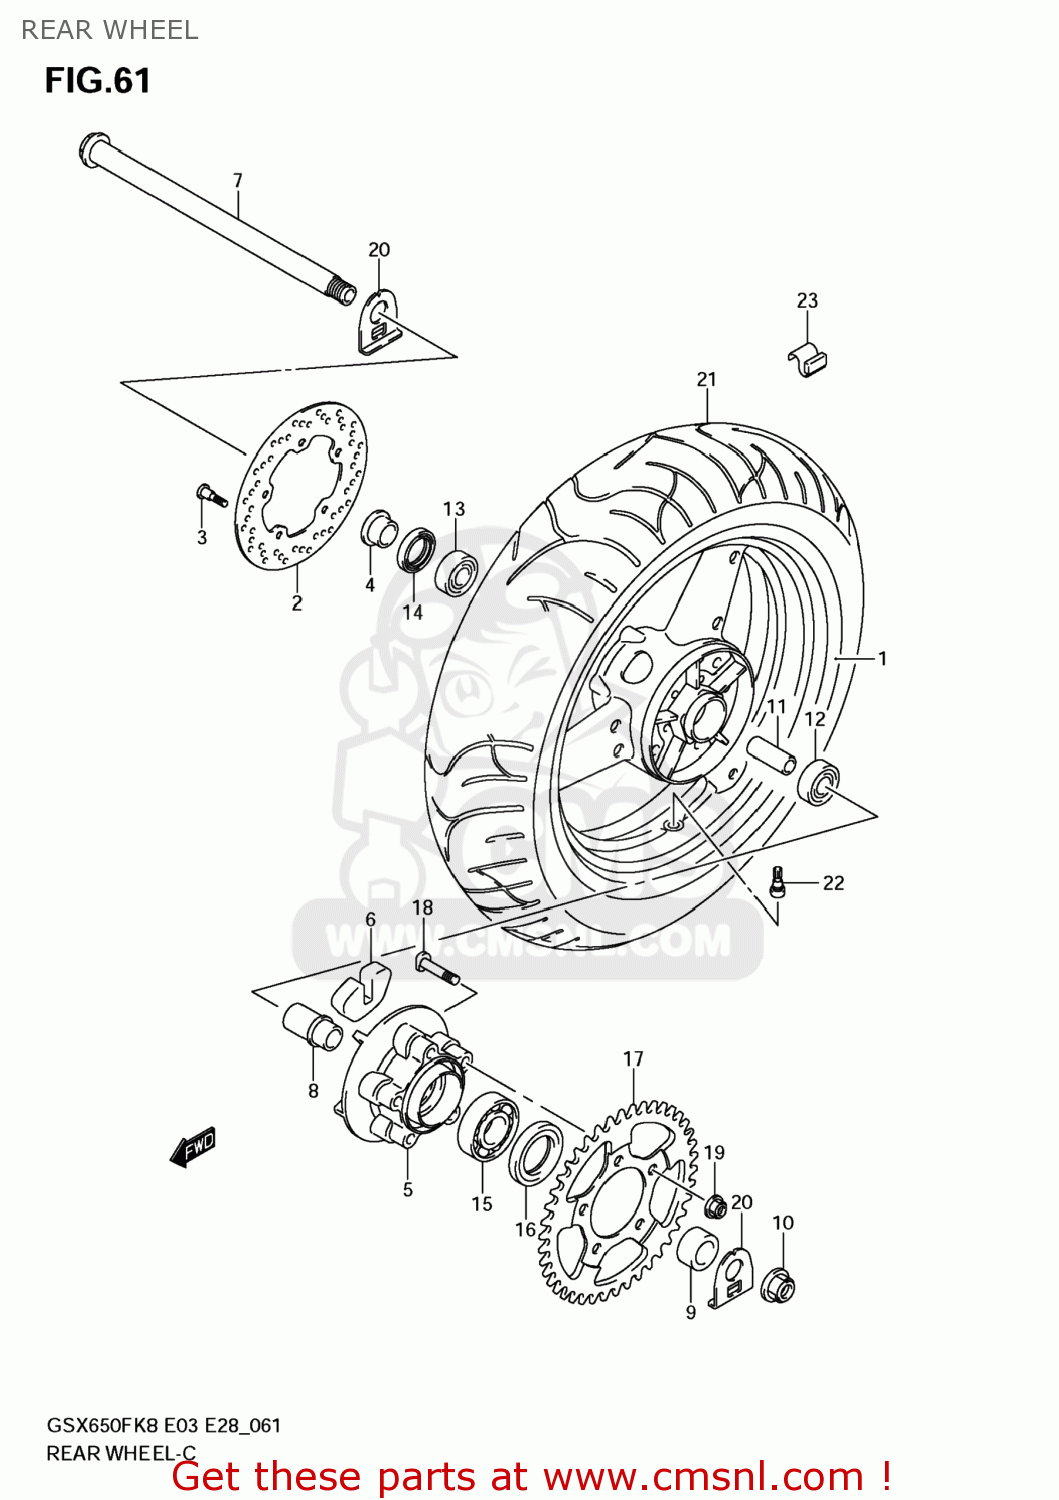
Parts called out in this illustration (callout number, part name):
1	WHEEL,RR(17M/CXMT5.00)
2	DISC,RR BRAKE
3	BOLT(8X33)
4	SPACER,RR AXLE,R
5	DRUM,RR SPROCKET
6	ABSORBER,RR HUB SHOCK
7	AXLE,RR
8	RETAINER,RR HUB BEARING
9	SPACER,RR AXLE,L
10	NUT
11	SPACER(20.5X28X88)
12	BEARING(20X47X14)
13	BEARING
14	SEAL,OIL(28X47X7)
15	BEARING(25X62X17)
16	SEAL,OIL(35X62X8)
17	SPROCKET,RR(NT:48-525)
18	BOLT(10X47)
19	NUT
20	WASHER,CHAIN ADJUSTER
21	TIRE,RR
22	VALVE ASSY,WHEEL RIM(TR412)
23	BALANCER,WHEEL(10G)
